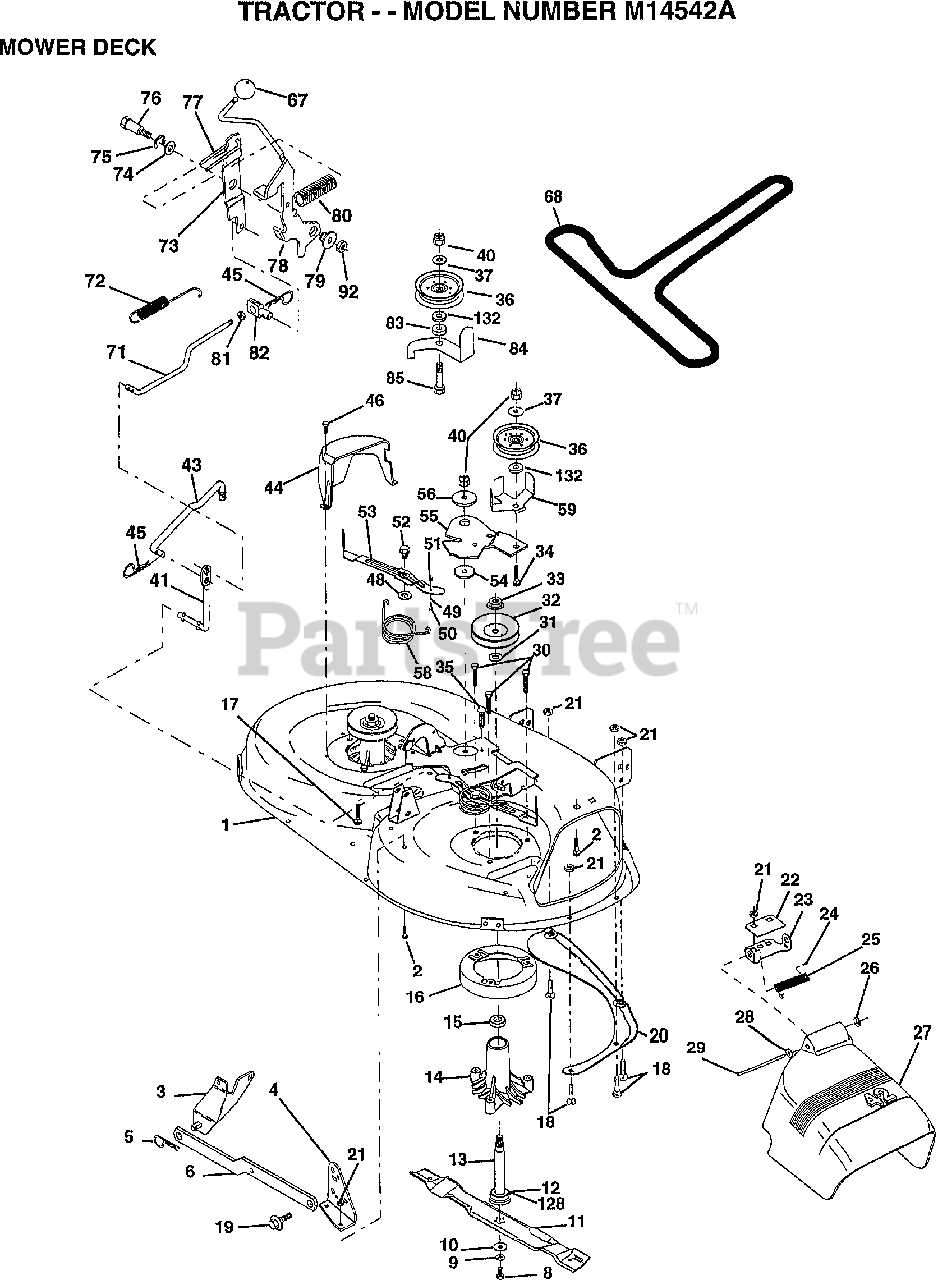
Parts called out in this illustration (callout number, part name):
1	DECK.WELD.42.
2	BOLT
3	BRKT ASM SWAY BAR
4	BRKT DECK SW BAR
8	BLADE BOLT
10	WASHER.HARD.BLADE
11	"BLADE.42"" HIPERF"
12	BEARING.BALL
14	HSG ASM MANDREL
15	BEARING
16	STRIPPER RND MWR
17	BOLT RDHD 3/8-16
18	BOLT
19	BOLT SHD 5/16-18
22	STIFFENER BRKT
23	DEFLECTOR BRKT
24	CAP-SLEEVE LT
25	SPRING TORSION
26	NUT PUSH M
27	DEFLECTOR.SHIELD
28	WASHER
29	HINGE ROD
31	WASHER
32	PULLEY.MANDREL.42
34	BOLT
35	XMAS TREE FASTNER
36	FLAT IDLER PULLEY
37	WASHER
41	PIVOT ROD
43	ROD CLUTCH W/NIBS
44	GUARD MAND LH BLK
45	RETAINER M
46	SCREW.1/4-20X5/8
48	HARD SMALL WASHER
49	ROLLER ASM-CAM
50	SHOULDER BOLT
51	LOCKNUT
52	BOLT.SHLD.5/16-18
54	HARDENED WASHER
55	ARM-IDLER
56	SPACER RETAINER
58	SPRING TORSN BRAK
59	GUARD IDLER TUV
67	KNOB
68	BELT.V.T-PATH
71	ROD CLUTCH 38/42
72	RETURN SPRING
73	CLUTCH ARM SECOND
74	WASHER
75	RING
76	SHOULDER BOLT
77	SPRING KEEPER
78	LEVER ASM-CLUTCH
79	BUSHING
80	SPRING.CLUTCH.MWR
81	NUT
82	TRUNION ADJ
83	WASHER
84	"KEEPER-BELT,FIXED"
85	BOLT RDHD 3/8-16
92	NUT
128	WASHER.FELT.
132	WASHER GT
